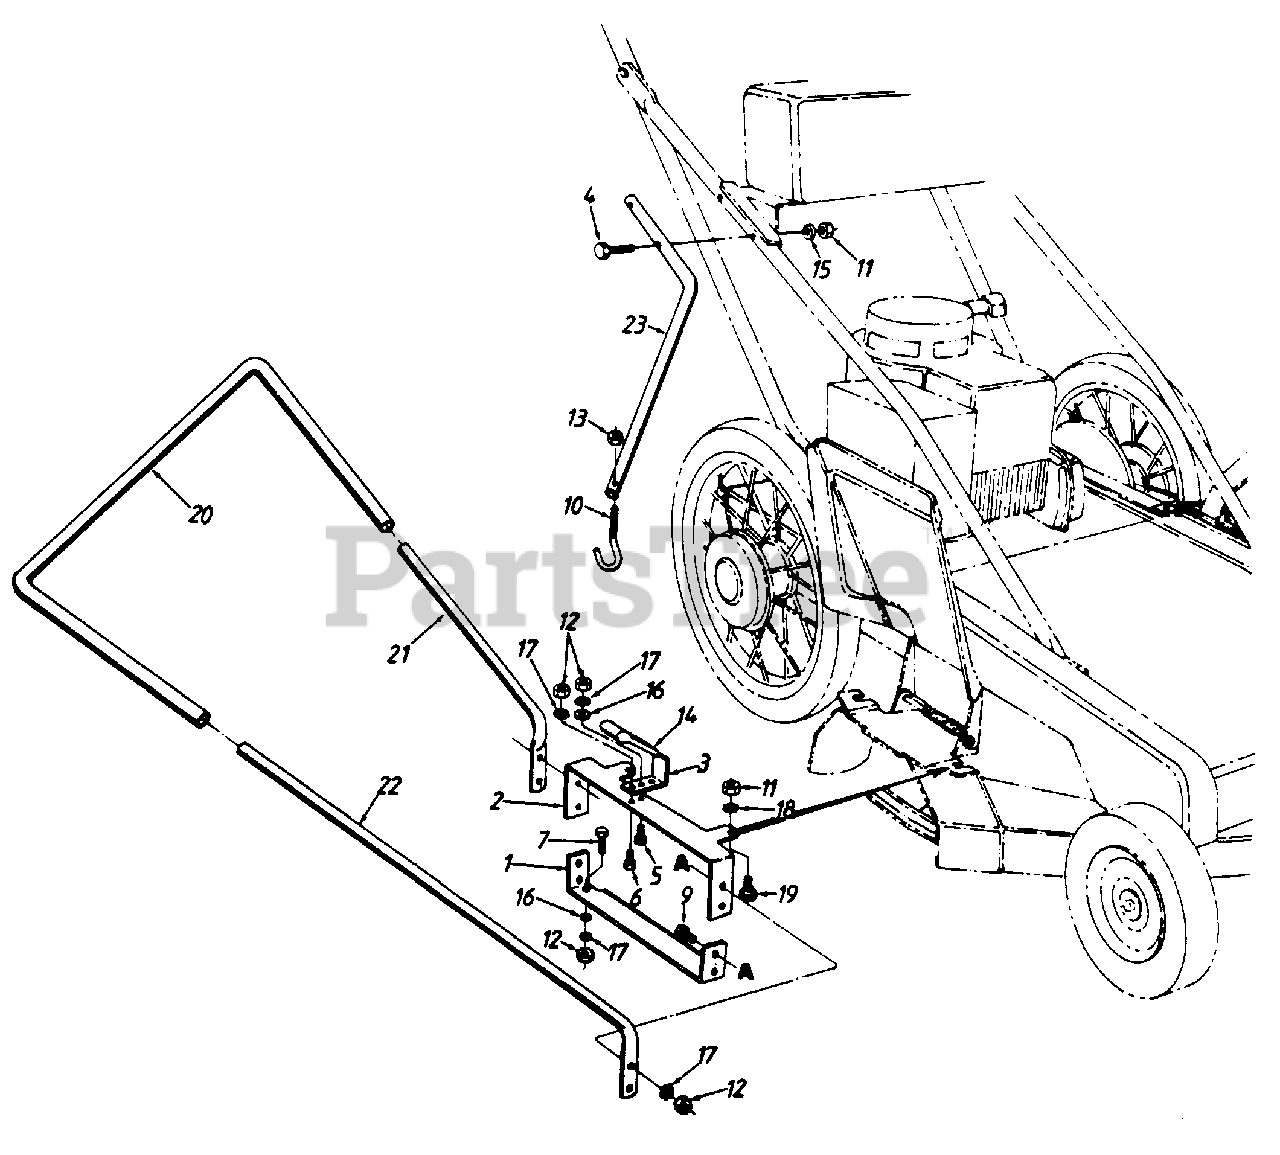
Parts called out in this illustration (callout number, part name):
1	Lower Opening Support
2	Upper Opening Support
5	Hex Bolt 1/4-20 x .85" Lg.
6	Hex Bolt 1/4-20 x .62" Lg.-
7	Hex Bolt 1/4-20 x .5" Lg.-
9	Hex Bolt 1/4-20 x 1.25 Lg.-
11	Hex Nut 5/16-18 Thd.-
12	Hex Nut 1/4-20 Thd.-
13	Hex Ins. Nut 1/4-20 Thd.
15	L-Wash. 5/16" I.D.
16	Fl-Wash. .281" I.D. x .5" O.D.
17	Ext. L-Wash. 1/4" I.D.
18	Ext. L-Wash. 5/16 I.D.
19	Shoulder Bolt
20	Upper Frame
21	Lower Frame
22	Lower Frame Arm
23	Holding Arm
